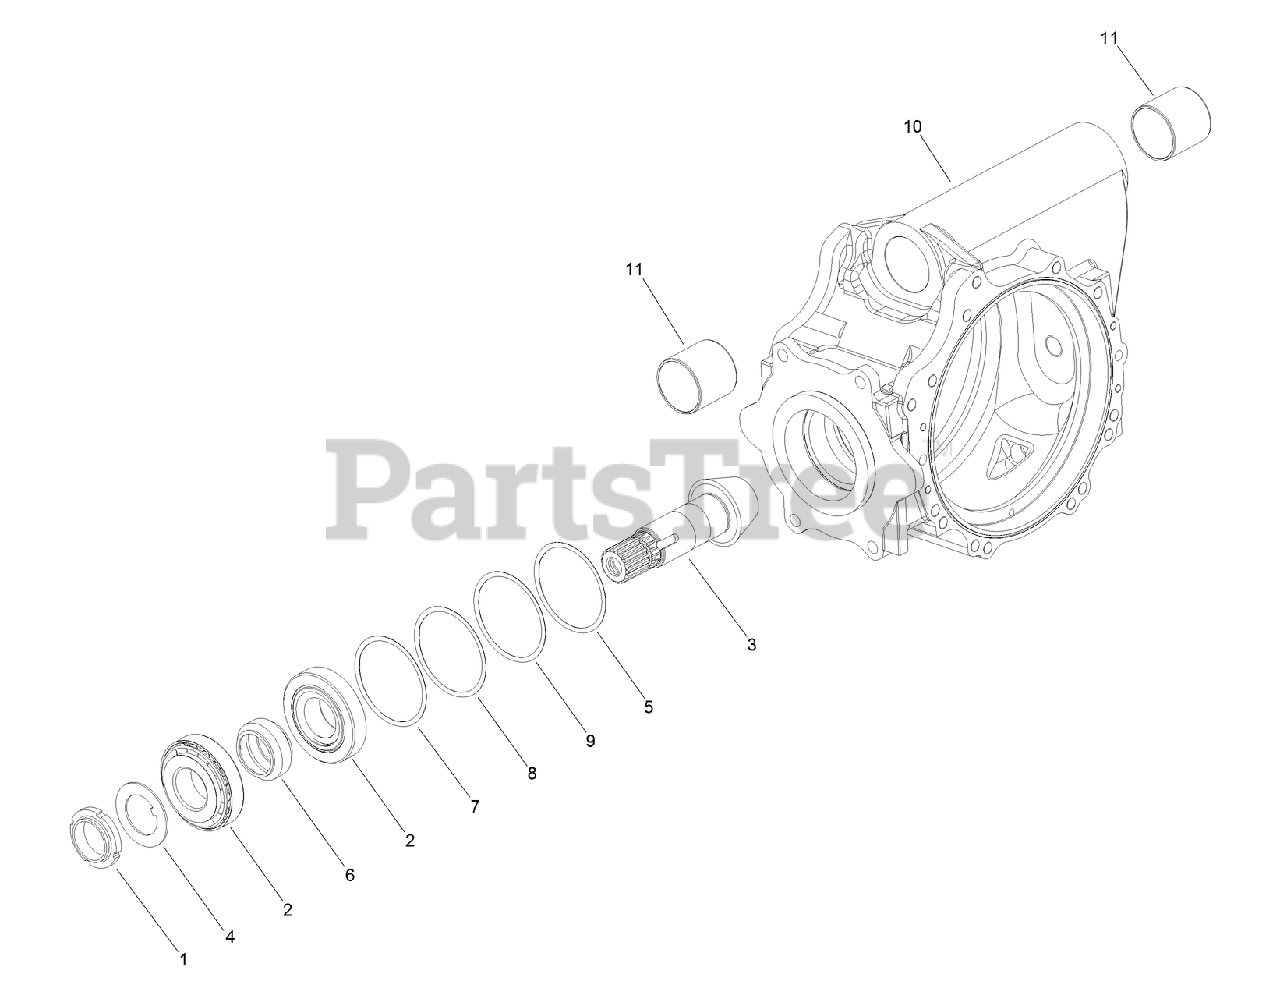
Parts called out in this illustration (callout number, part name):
1	NUT-LOCK
2	BEARING-ROLLER, TAPER
3	PINION-BEVEL
4	WASHER-ROTATION, ANTI
5	SHIM (0.5)
6	SPACER-DEFORMABLE
7	SHIM (0.35)
8	SHIM (0.3)
9	SHIM (0.4)
10	HOUSING-CENTRAL, UPPER PIVOT
11	BUSHING
